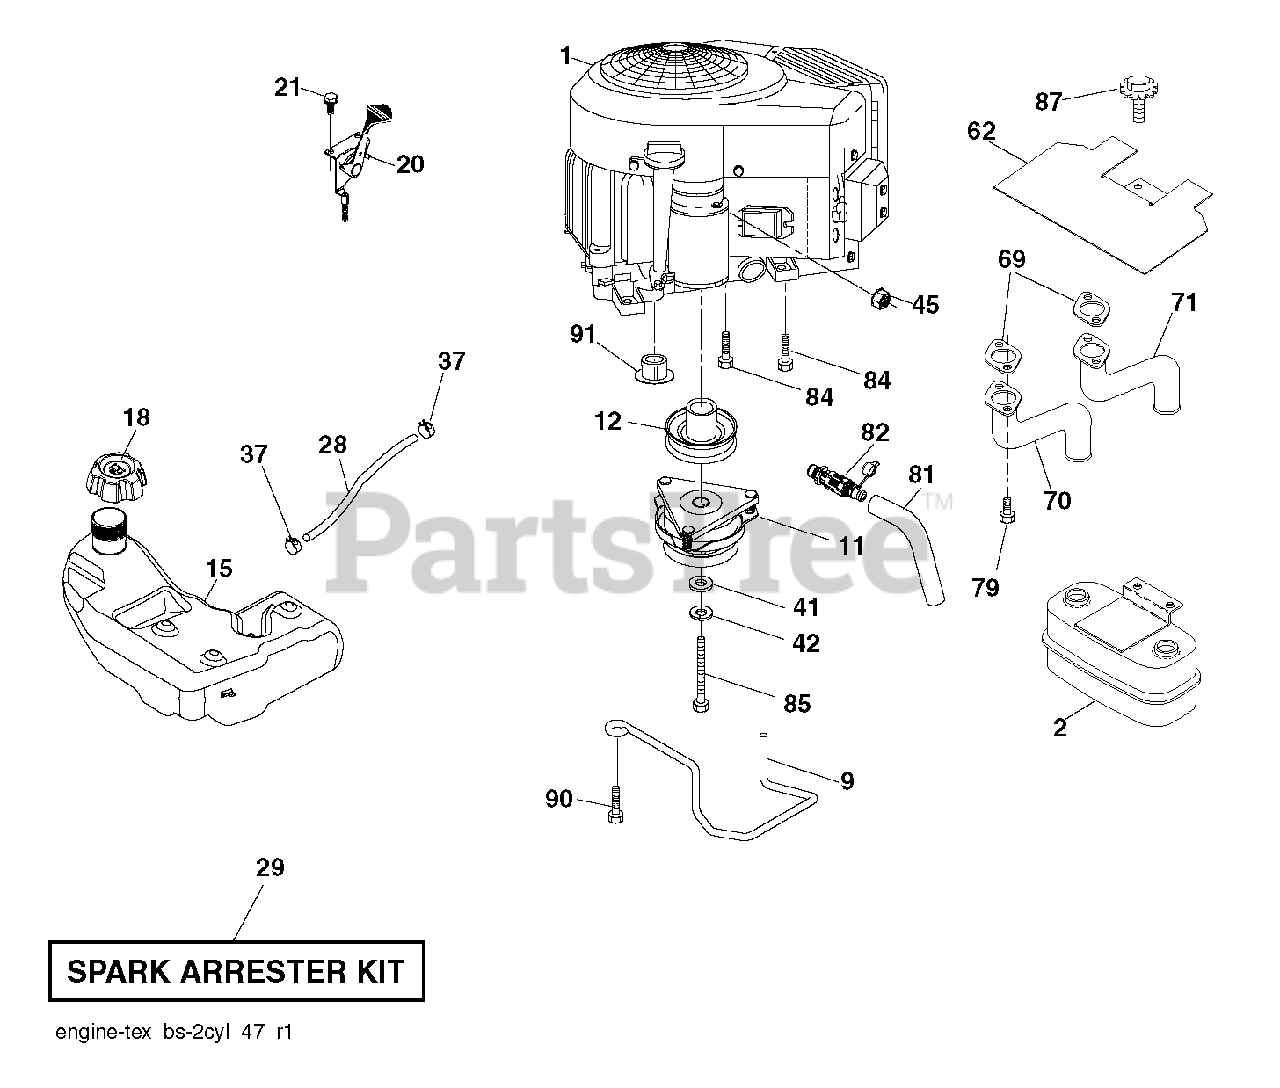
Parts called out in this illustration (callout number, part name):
2	MUFFLER.TWIN.CYL.LOW.TONE
9	KEEPER.BELT.ENGINE.4.2
11	CLUTCH
12	PULLEY.ENGINE.TUFFTORQ
15	TANK.FUEL.4GAL
18	CAP.ASM.FUEL.TANK.3"BLACK
20	CONTROL.TH/CK.COBRA.B&S.TWN.
21	SCREW.#10 X 0.750.BOS THREAD
29	ARRESTER SPARK (OPTIONAL)
37	HOSE CLAMP
42	LOCKWASHER
45	NUT
62	SHIELD.HEAT.MUFFLER
69	GASKET.MUFFLER
70	TUBE MANIFOLD LH
71	EXHAUST TUBE RH
79	SCREW.SOCKET.HEAD.5/16-18
81	TUBE, DRAIN OIL ASM.
82	VALUE.OIL.DRAIN
84	SCREW.3/8-16
85	BOLT HEX 7/16-20X4-1/4"
87	BOLT, 5/16-18 X 1 3/4
90	SCREW 3/8-16X1
91	BUSHING.1.375OD
